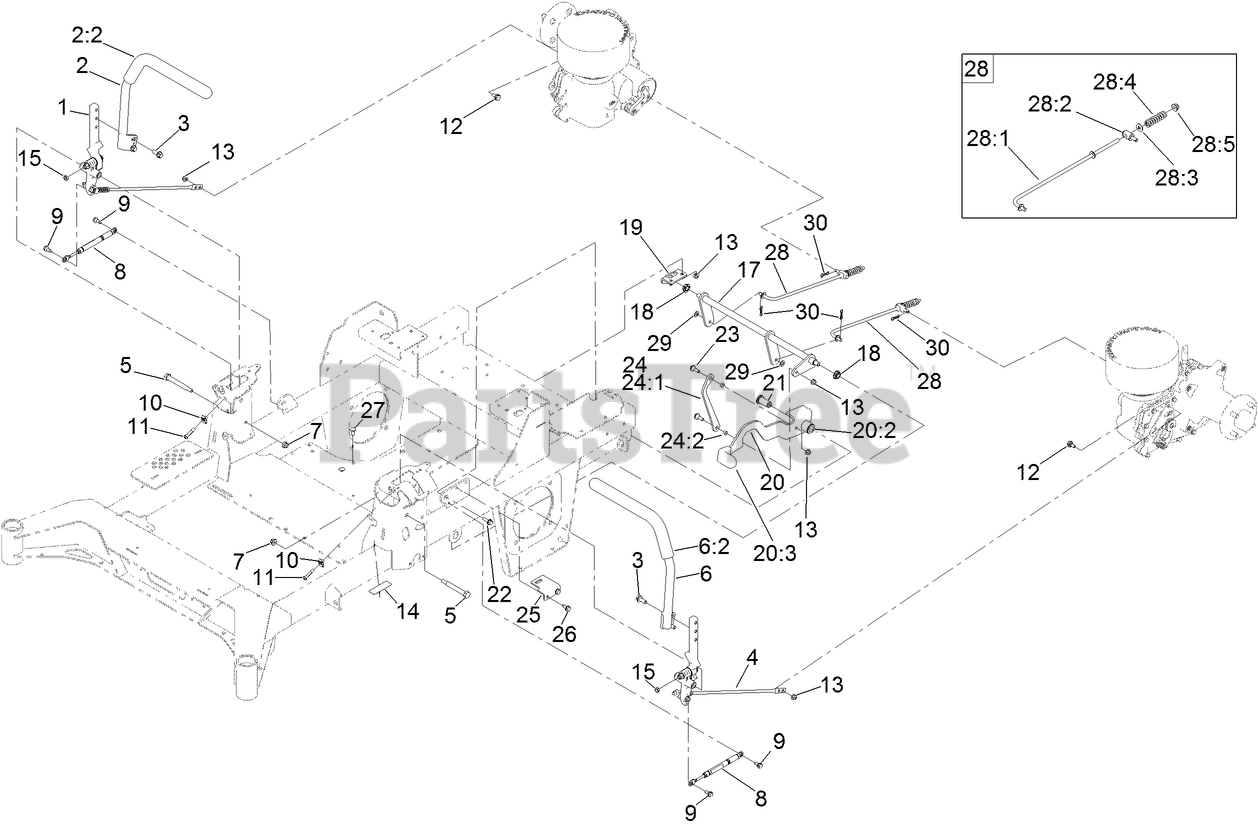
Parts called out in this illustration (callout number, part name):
1	MOTION CONTROL ASM-RH
2	HANDLE ASM - RH
2:2	GRIP-CONTROL, LEVER
3	SCREW-HHF
4	MOTION CONTROL ASM-LH
5	BOLT-PIVOT
6	HANDLE ASM - LH
6:2	GRIP-CONTROL, LEVER
7	NUT-HF, NI
8	DAMPER
9	SCREW-SHOULDER
11	SCREW-HSBH
12	BOLT-SHOULDER,HFH
13	NUT-HF, NI
14	DECAL-BRAKE, PARKING
15	NUT-JAM
17	BRAKE ASM
18	BEARING-SPHERICAL
19	BRACKET-BRAKE
20	BRAKE LEVER ASM W/GRIP
20:2	BUSHING-FLANGE
20:3	GRIP-LEVER
21	PIVOT-HANDLE
22	SCREW-HHF
23	SCREW-SHOULDER
24	BRAKE LINK ASM
24:1	PLATE-LINK, HANDLE
24:2	BUSHING-SLEEVE
25	PLATE-SWITCH
26	SCREW-HWHTF
27	SCREW-CARR
28	BRAKE ROD ASM
28:1	ROD-BRAKE
28:2	FITTING-ROD
28:3	WASHER-FLAT
28:4	SPRING-COMPRESSION
28:5	NUT-HF, NI
29	WASHER-FLAT
30	PIN-COTTER, LOCKING
